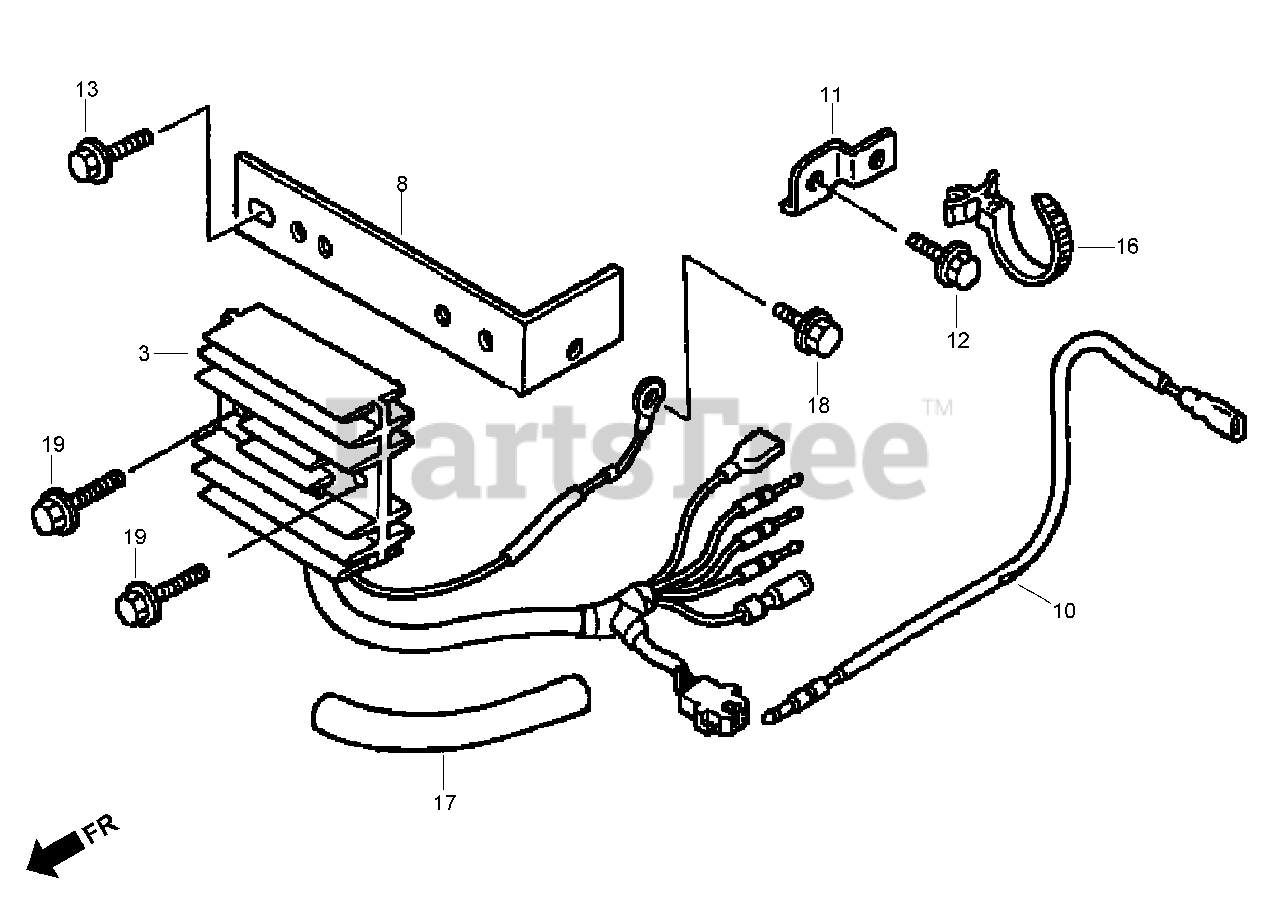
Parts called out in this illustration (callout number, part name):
3	REGULATOR RECTIFIER ASM
8	BRACKET-REGULATOR
10	SUB-WIRE HARNESS ASM
11	BASE-CLIP
12	BOLT-FLANGE (6X12) (C T200)
13	BOLT-FLANGE (6X14) (C T200)
16	STRAP-CABLE (105MM) (N H1 BLACK)
17	TUBE-WIRE
18	BOLT-FLANGE (6X8)
19	BOLT-FLANGE (6X20)
